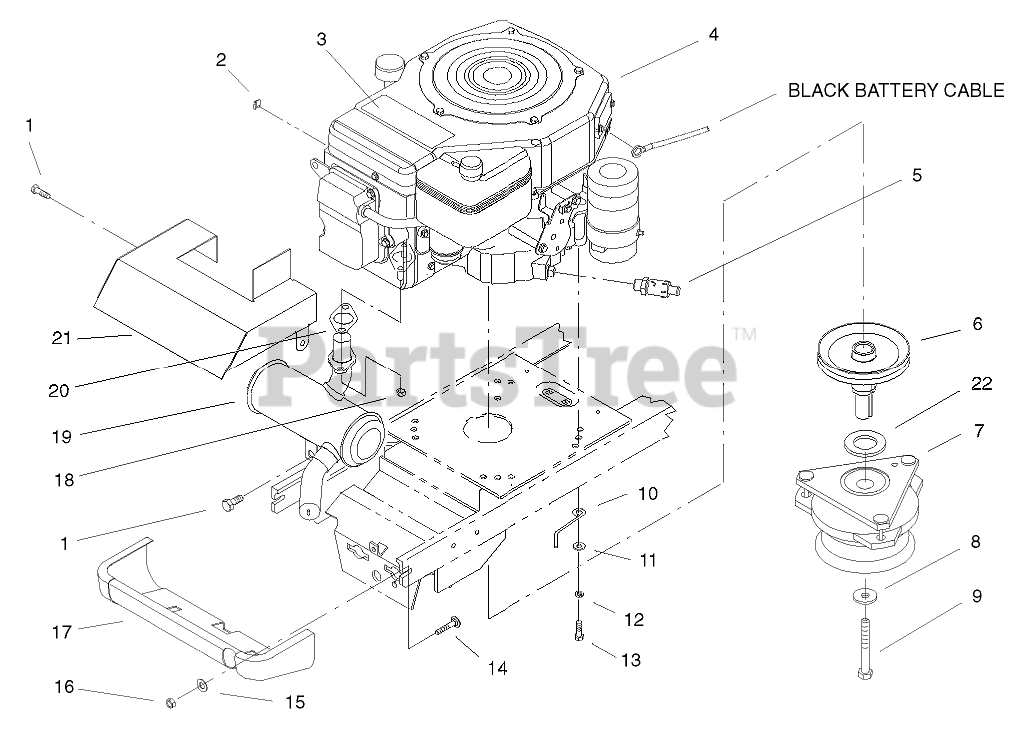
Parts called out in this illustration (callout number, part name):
1	SCREW-HWHTF
2	CLIP-RETAINER, WIRE
3	DECAL - LOGO
4	ENGINE - KOHLER 15
5	VALVE-DRAIN, OIL
6	PULLEY- ENGINE GEAR
7	CLUTCH-PTO
8	WASHER
9	SCREW-HH
10	GUIDE-BELT
11	WASHER-PLAIN
12	WASHER-LOCK
13	SCREW-HH
14	BOLT-CARR
15	WASHER-FLAT
16	NUT-LOCK, NI
17	MUFFLER SHIELD ASM
18	NUT-HF
19	MUFFLER
20	Gasket-Exhaust
21	SHIELD-MUFFLER
22	SPACER-CLUTCH
